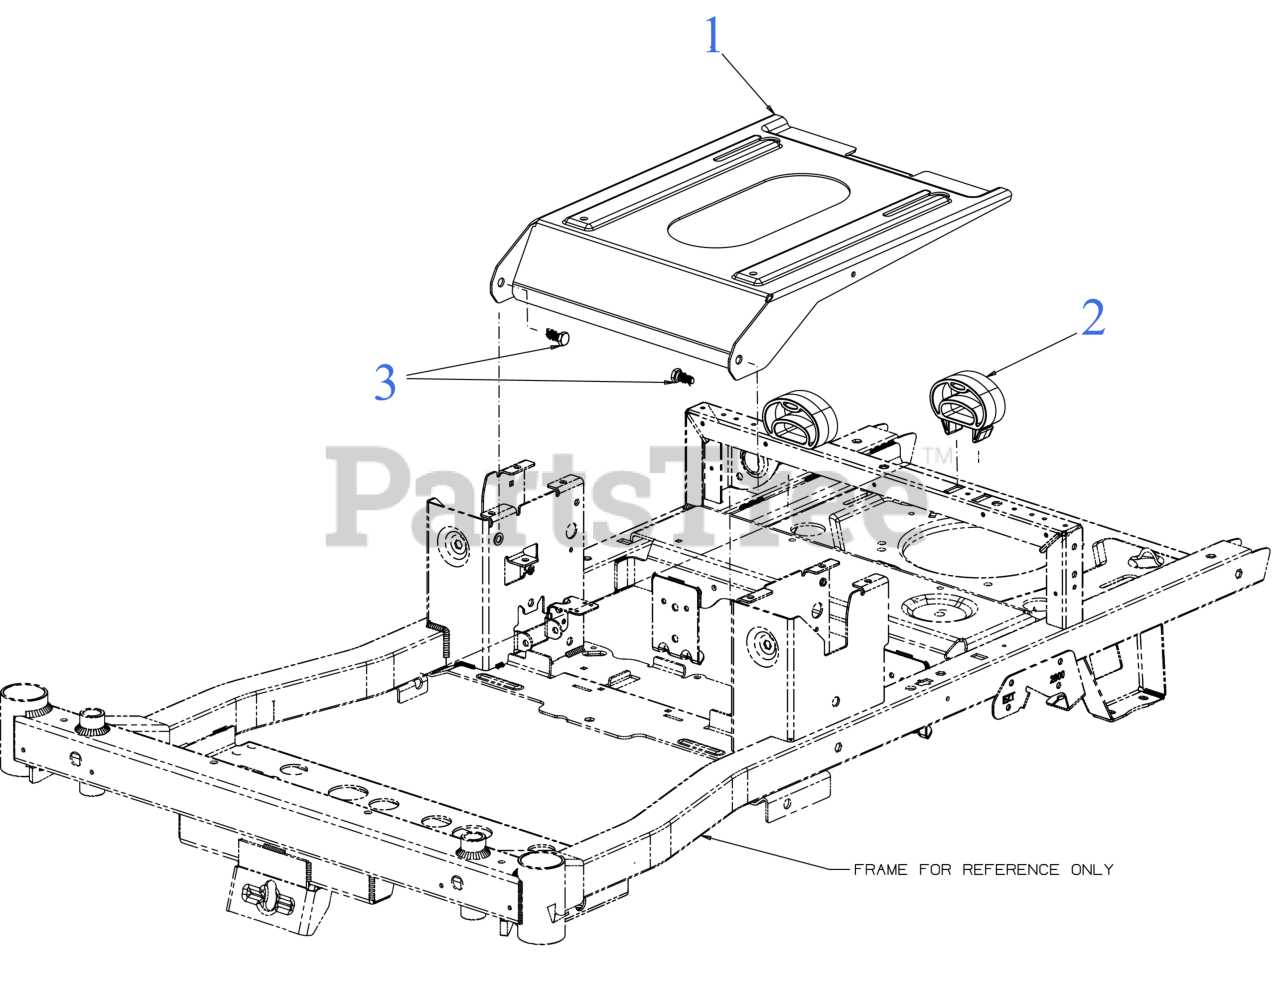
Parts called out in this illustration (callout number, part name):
1	SEAT BASE PLATE
2	POLYMER SEAT SPRING
3	SHOULDER SCREW .44DIAx.18 5/16-18
